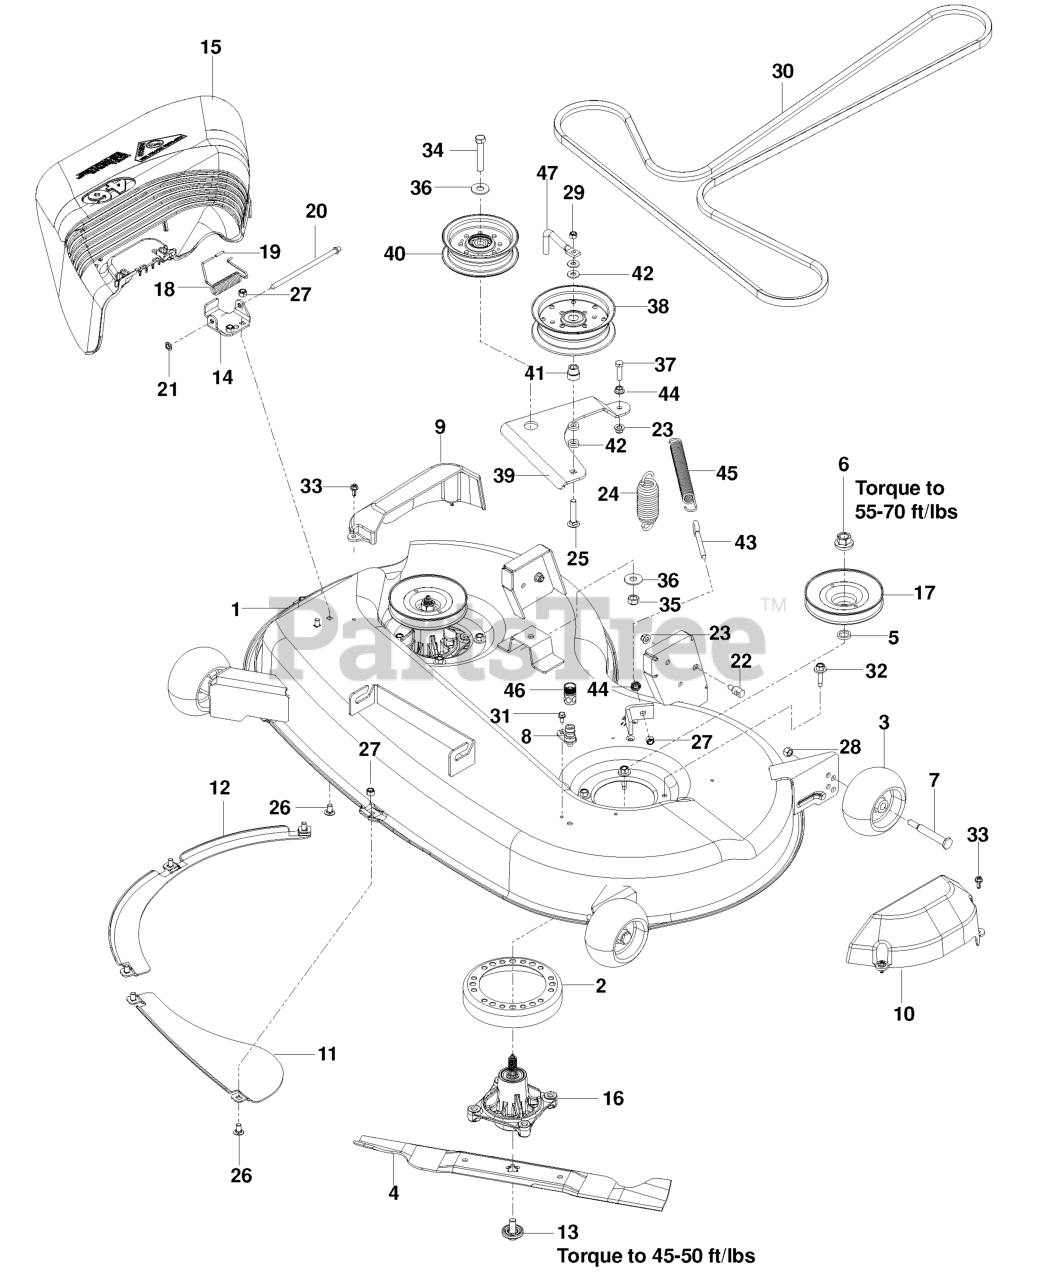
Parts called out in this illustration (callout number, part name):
1	DECK W/DECALS - SZ44
2	STRIPPER-ROUND-UNIVERSAL
3	GAUGE WHEEL
4	BLADE.MOWER.46".HI.LIFT
5	WASHER-SPACER
6	LOCKNUT - 9/16
7	SHOULDER BOLT 1/2X2-5/8 ZD SPE
8	PORT.WASHOUT
9	COVER.MANDREL.RH.46"
10	COVER.MANDREL.LH.46"
11	BAFFLE CENTER FRONT
12	BAFFLE FRONT RH
13	BOLT.WASHER.ASM.7/16-2
14	BRKT.DEFLECTOR.38"2005+
15	SHIELD.DEFLECTOR.MOWER.46"BLAC
16	CUTTER HOUSING
17	RP.PULLEY, DECK
18	TORSION SPRING
19	CAP-SLEEVE
20	ROD, HINGE
21	PUSH NUT
22	STUD.FASTNER.W/ANTI-ROTATE
23	5/16-18 NYLOC FLANGE NUT
24	SPRING
25	CARRIAGE BOLT 3/8-16 X
26	BOLT 5/16C X 3/4" CARRIAGE
27	NUT 5/16 NYLOC
28	NUT 3/8-16 NYLOC
29	NUT HEX 3/8-16 NYLON, THIN
31	BOLT 1/4-20 X 1/2 HWST
32	WASHER HEAD SCREW
33	SCREW- 1/4-20 X 5/8
34	BOLT 7/16-14 X 2-1/2 GR 5 ZD
35	7/16-14 HEX NUT W/NYL RING ZD
36	WASHER 7/16 FLAT ZD
37	HCS 5/16C X 1 1/4
38	PULLEY, IDLER
39	ARM, IDLER BLK
40	PULLEY.IDLER.MWR.STATI.LH
41	IDLER BUSHING
42	WASHER 3/8 X 3/4 X .187 TK
43	EYE BOLT 5/16 X 3.50
44	NUT 5/16C WHIZ
45	SPRING, DECK BELT
46	COUPLING.QUICK CONNECT
47	BELT KEEPER 5"
